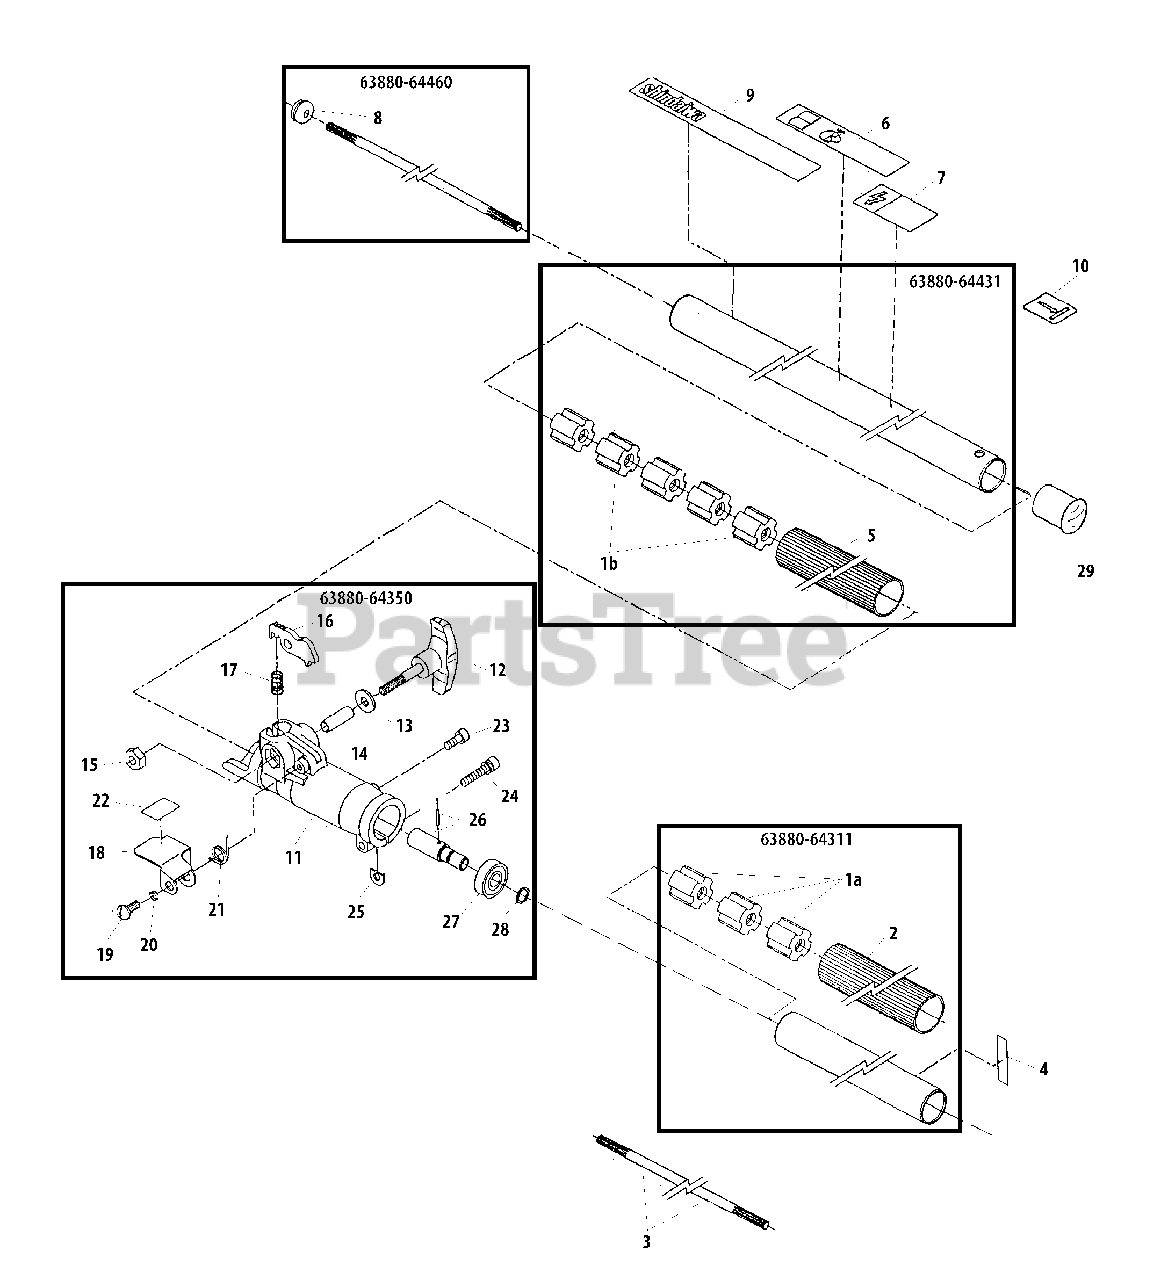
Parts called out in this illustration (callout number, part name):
3	PIPE, MAIN
4	LABEL - HANDLE LOCATION
5	GRIP
6	LABEL - CAUTION
7	LABEL - CAUTION
8	GROMMET
9	LABEL - MODEL
10	LABEL - HIGH VOLTAGE
11	COUPLER
12	KNOB
13	WASHER
14	COLLAR
15	NUT
16	LEVER, LOCK
17	SPRING
18	COVER
19	SCREW - 5X12
20	COLLAR
21	SPRING
22	LABEL - LATCH INSTRUCTION
23	SCREW - 5X12
24	SCREW - 5X25
25	SHIM
26	CONNECTOR, SHAFT
27	BEARING, BALL - 609ZZ
28	RING, RETAINING
29	CAP
63880-64311	MAIN PIPE ASSY
63880-64350	COUPLER ASSY
63880-64431	MAIN PIPE ASSY
63880-64460	DRIVESHAFT ASSY
